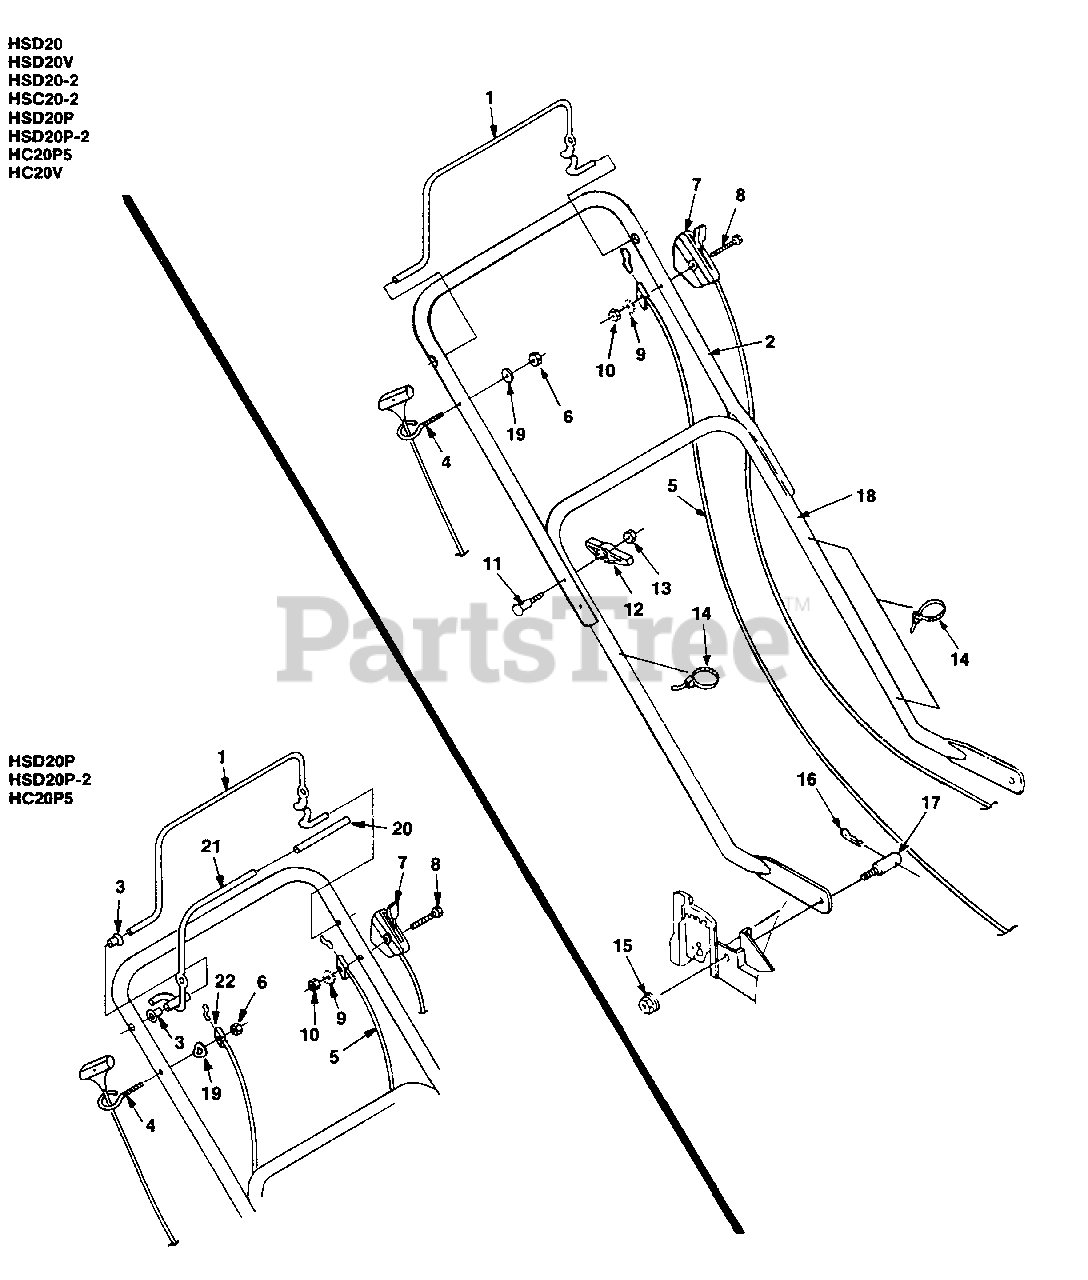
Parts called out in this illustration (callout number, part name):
1	BAIL- Engine control
2	HANDLE- Upper
3	BUSHING- Traction bail
5	CONTROL- Engine
6	NUT- Lock 1/4-20
7	CONTROL- Throttle
8	SCREW- Hex cap
9	WASHER- Ext. tooth
10	NUT- Hex (1/4-20)
11	BOLT- Handle joining
12	KNOB- Handle
13	NUT- Hex (5/16-18)
14	CABLE- Tie
15	NUT- Flange (5/16-18)
16	PIN- Hair
17	STUD- Handle mtg.
18	HANDLE- Lower
19	WASHER
20	SLEEVE- Traction
21	BAIL- Traction
22	CONTROL- Traction
